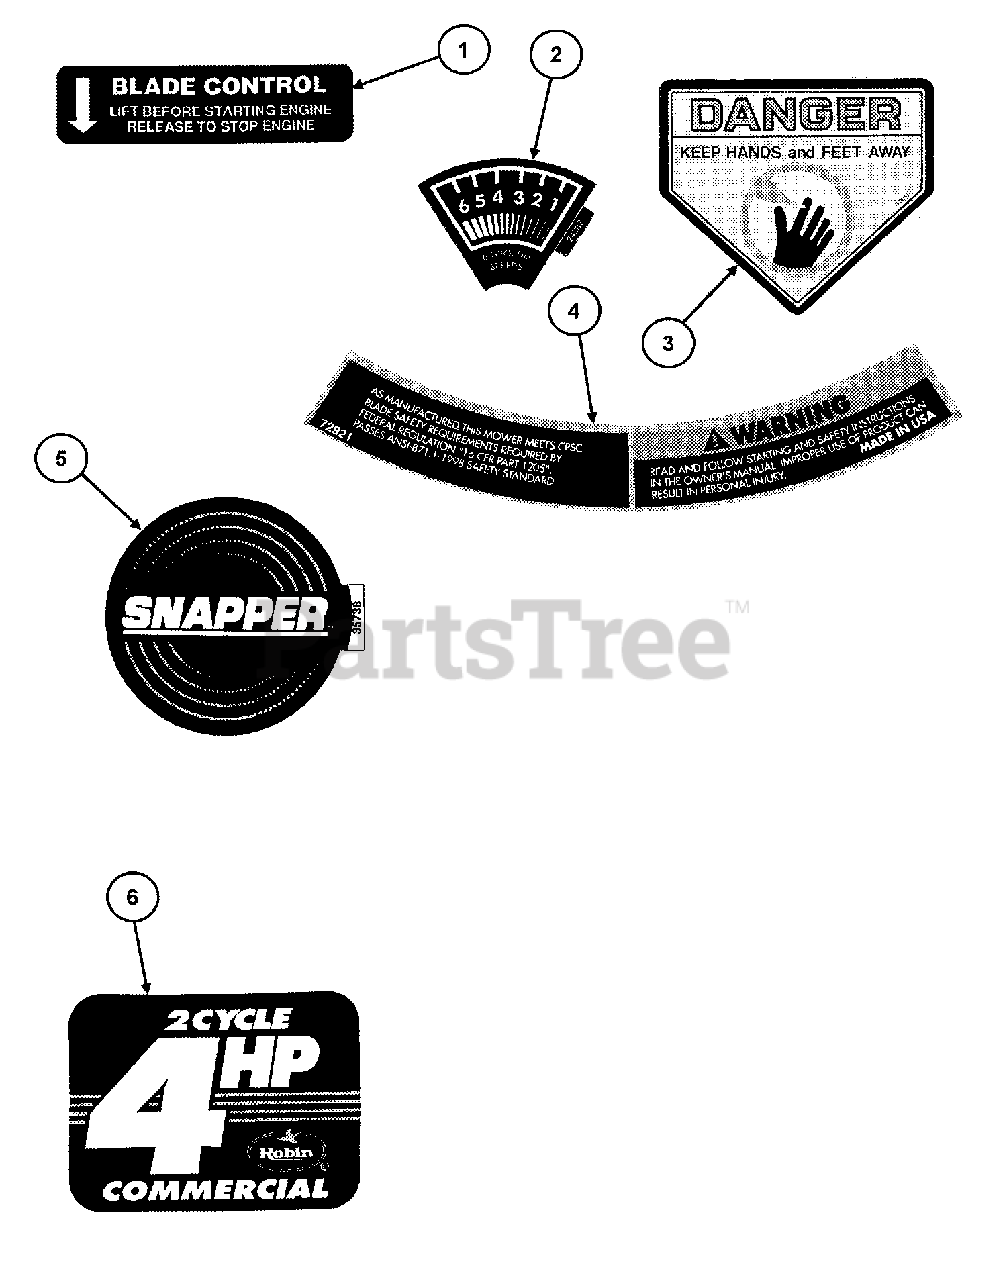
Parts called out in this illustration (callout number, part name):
1	DECAL, Blade Control
2	DECAL, Speed Select
3	DECAL, Danger, Cut Finger
4	DECAL, Deck Warning
5	DECAL, SNAPPER (3.38 Dia.) (Black & Gold)
6	DECAL, 4HP 2CY (Black & Gold)
